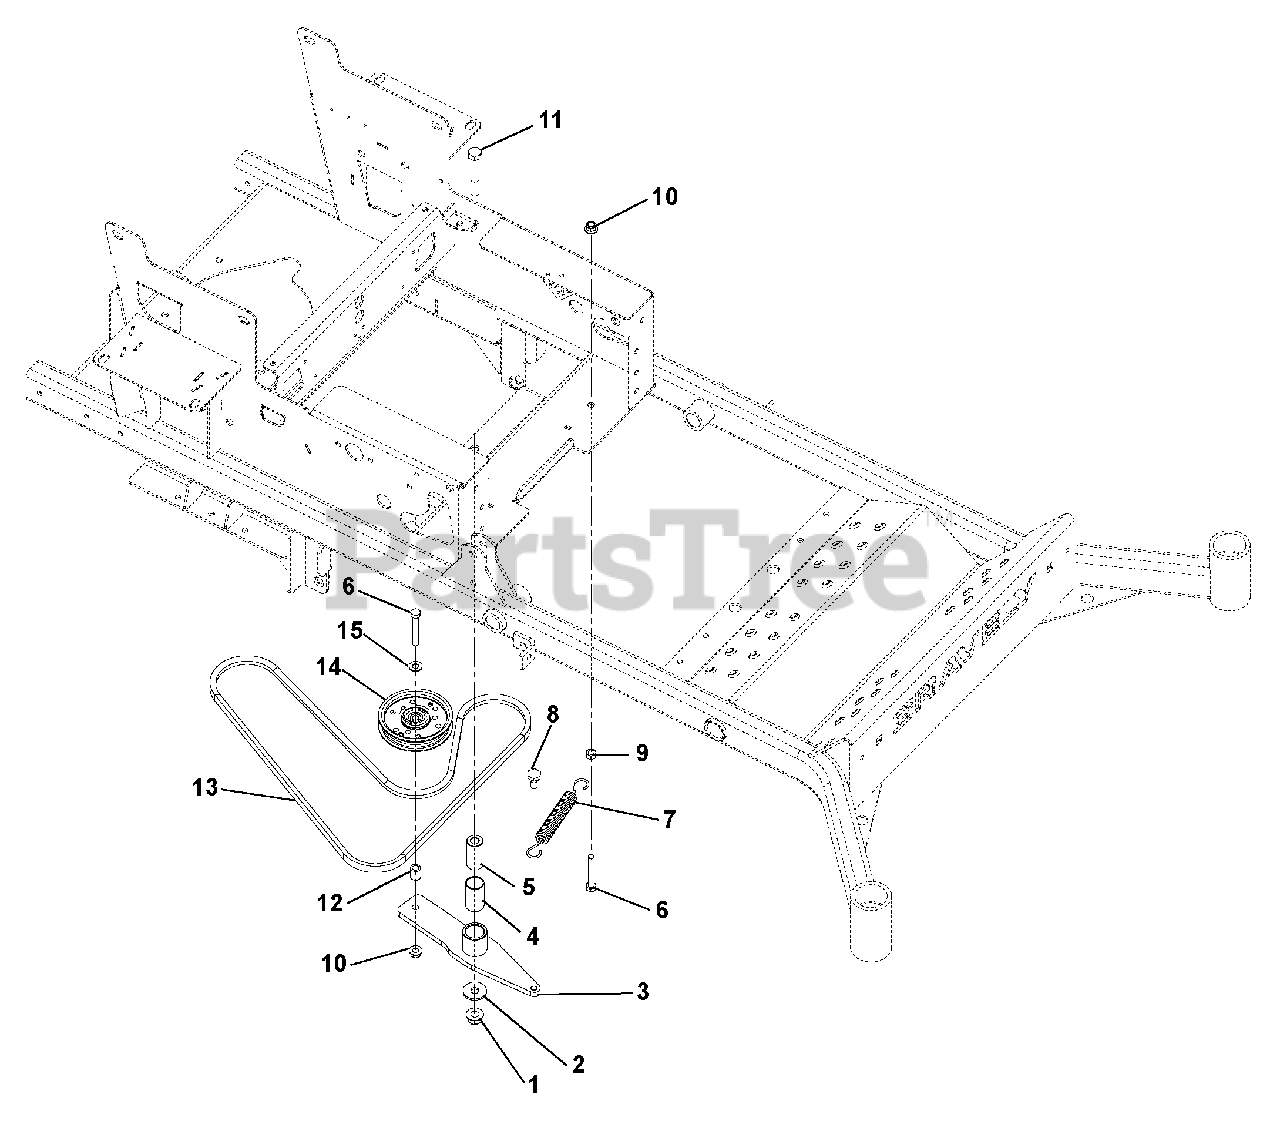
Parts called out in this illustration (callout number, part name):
1	Nut, .50-13 Nyloc Flange
2	Washer, Flat Steel .511 x 1.441 x .125
3	Weldment, Hydro Drive Idler Arm
4	Bushing, 1.00 x 1.125 x 1.936
5	Bushing, Spacer .505/.500 x .999/.996 x 2.05/2.03 Promaster
6	Bolt, Hex .38-16 x 2.50 Grade 5
7	Spring, Extension
8	Bolt, Shoulder EP .38-16 x .30 Hex
9	Nut, Hex .38-16
10	Nut, .38-16 Nyloc Flange
11	Bolt, Hex .50-13 x 3.25 Grade 5
12	Bushing, Sleeve .407 x .625 x .750
13	Belt, A 69.26 Raw Cogged
14	Idler, Flat 4.00 x .38
15	Washer, Flat-Steel .406 x .812 x .065
